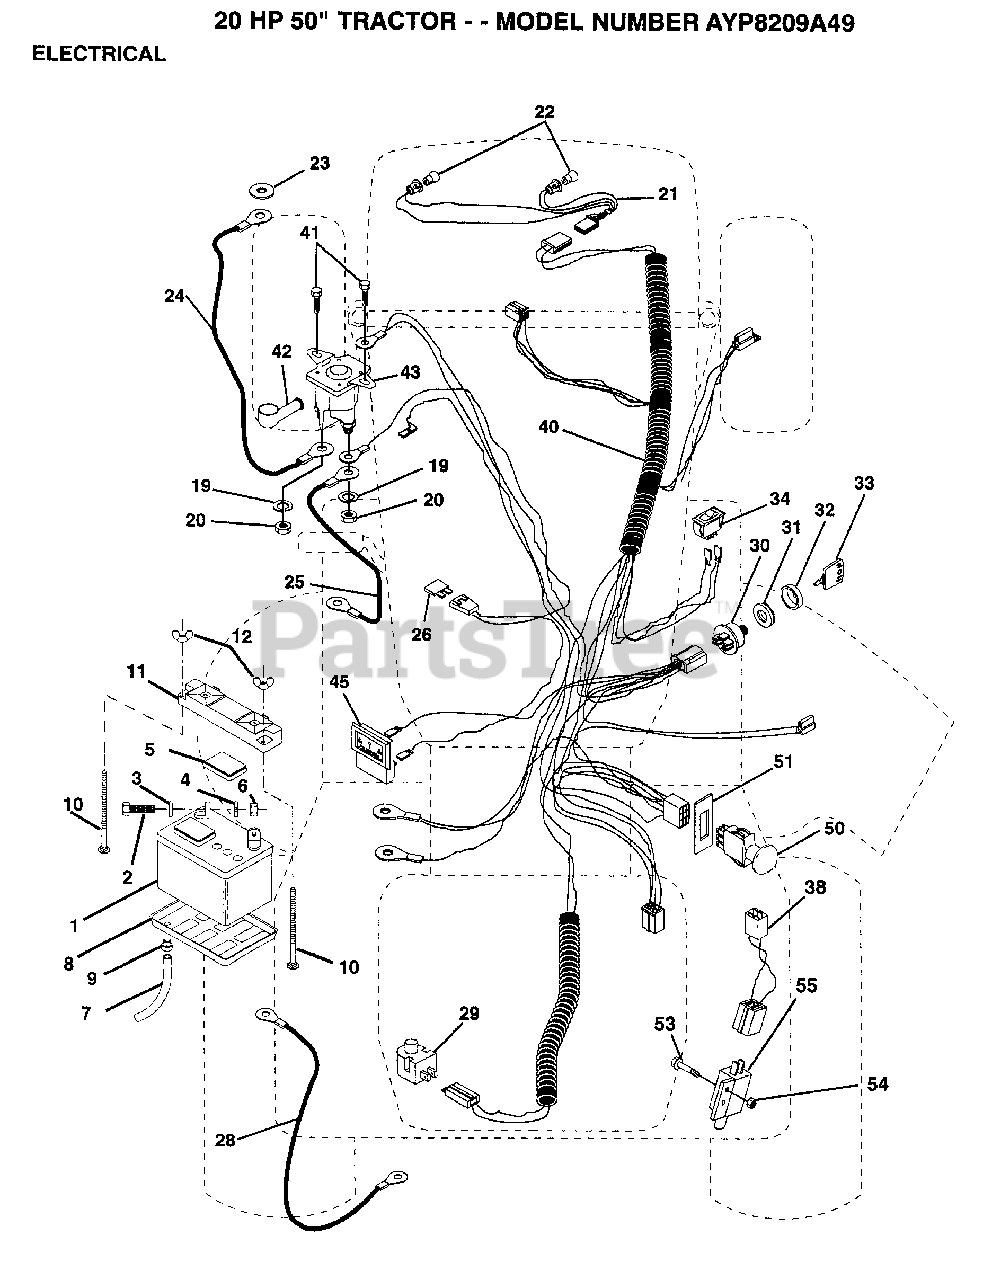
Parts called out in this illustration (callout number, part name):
2	BOLT LT
3	WASHER
4	LOCKWASHER
5	"CAP,BATTERY "
7	"DRAIN TU T, BATT"
8	"TRAY T, BATTERY"
9	HOSE CLAMP T
10	BOLT
20	NUT
22	HEADLAMP BULB
23	LOCKWASHER
24	"CABLE T, BATTERY"
25	CABLE-BATTERY T
26	FUSE HYT
28	CABLE T
29	SWITCH SEAT
32	COVER KEY SWITCH
33	KEY MLD GEN DELTA
34	SWITCH LT
38	ADAPTER.HARN.SERV
40	HARNESS IGN GT
41	SCREW
45	AMMETER
51	RING RETAIN PTO
53	SCREW
54	"NUT,KEPS"
55	SWITCH-INTER. GT
